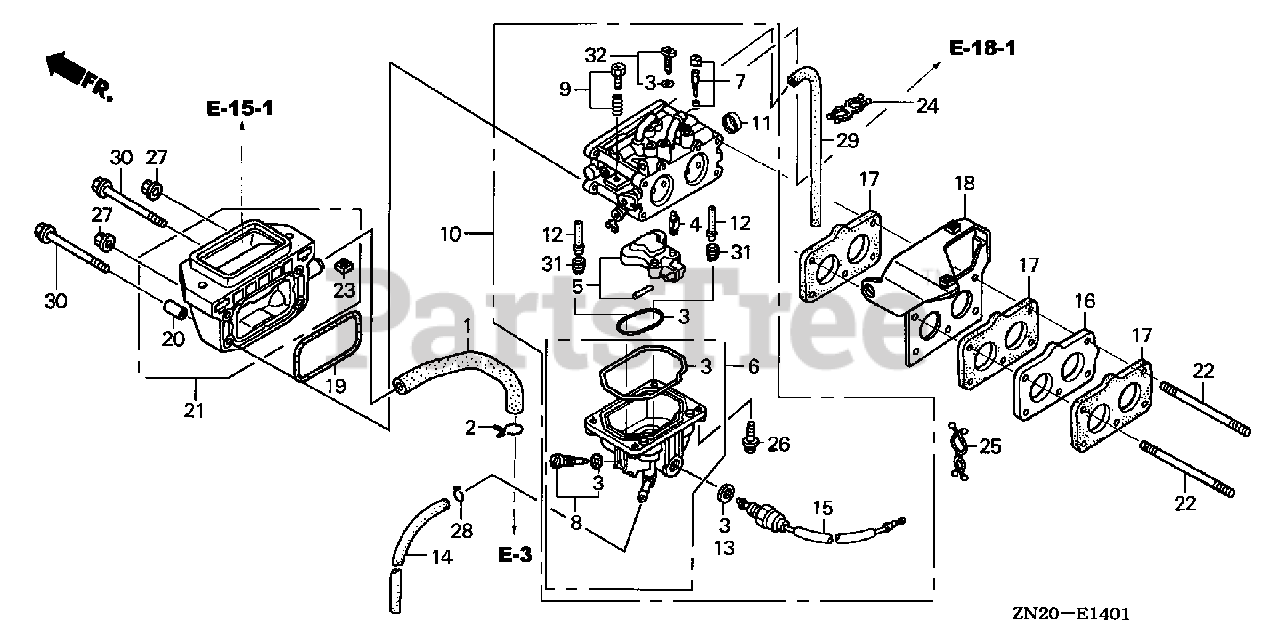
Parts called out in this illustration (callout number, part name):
1	TUBE, BREATHER
2	CLIP, BREATHER TUBE
3	GASKET SET
4	VALVE SET, FLOAT
5	FLOAT SET
6	CHAMBER SET, FLOAT
7	SCREW SET (PILOT)
8	SCREW SET, DRAIN
9	SCREW SET (TH.STOP)
10	CARBURETOR ASSY. (BK02B A)
11	CAP, CHOKE LEVER DUST
12	NOZZLE, MAIN
13	WASHER, PLAIN
14	TUBE, DRAIN
15	VALVE ASSY., SOLENOID
16	INSULATOR, CARBURETOR
17	GASKET, CARBURETOR
18	STAY, FUEL PUMP
19	GASKET, AIR CLEANR
20	COLLAR A, AIR CLEANER
21	ELBOW, AIR CLEANER
22	BOLT, STUD (6X113)
23	NUT, INSERT (6MM)
24	CLIP, WIRE HARNESS
25	CLIP, PURSE LOCK
26	SCREW, PAN (4X12)
27	NUT, FLANGE (6MM)
28	CLIP, TUBE (B8)
29	BULK HOSE, VACUUM (4.5X1000) (4.5X540)
30	BOLT, FLANGE (6X115)
31	JET, MAIN (#90)
31	JET, MAIN (#92)
31	JET, MAIN (#95)
32	JET SET, PILOT (#40)
